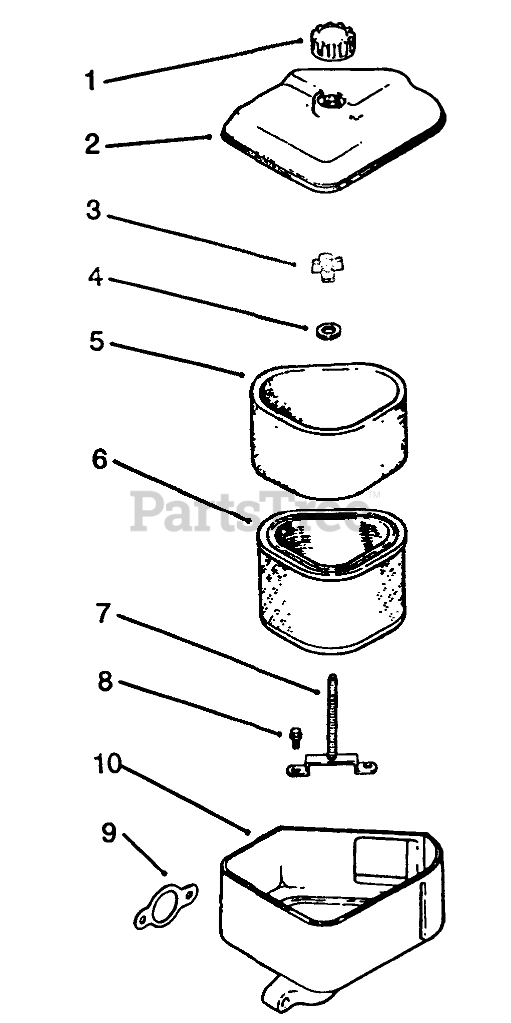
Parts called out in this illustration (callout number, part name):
1	Knob-Air Cleaner Cover (Only On: 72042, 72063,72062,72043)
2	Cover-Air Cleaner (Only On: 72042, 72063, 72062, 72043)
3	Nut-Wing (Only On: 72042, 72063, 72062, 72043)
4	Washer-Flat (Only On: 72042,72063, 72062, 72043)
5	Element-Air Cleaner (Only On: 72042, 72063, 72062, 72043)
6	Precleaner-Element (Only On: 72042, 72063, 72062, 72043)
7	Stud-Mounting Plate (Only On: 72042, 72063, 72062, 72043)
8	Screw-Mounting Plate (Only On: 72042, 72063, 72062, 72043)
9	Gasket-Air-Cleaner (Only On: 72042, 72063, 72062, 72043)
10	Base-Air Cleaner (Only On: 72042, 72063, 72062, 72043)
